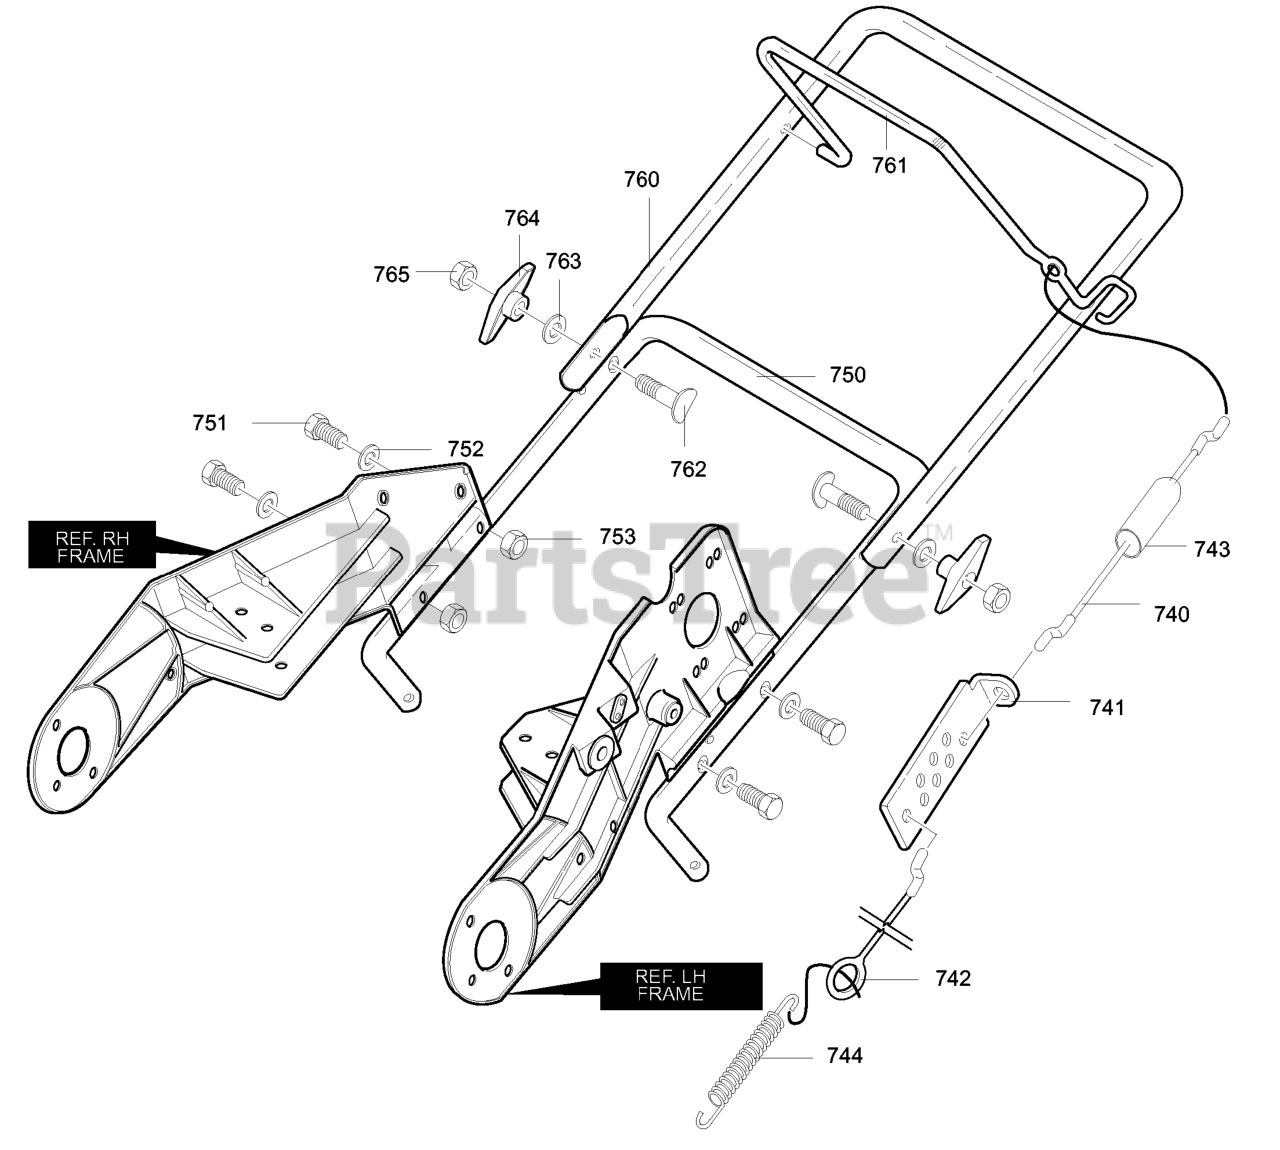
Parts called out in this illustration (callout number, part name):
740	CABLE, UPPER CONTROL
741	LF BRKT, CABLE ADJ
742	CABLE, LOWER CONTROL
743	BOOT, CLUTCH SPRING
744	SPRING, EXTENSION
750	HANDLE, LOWER
751	SCREW, 1/4-20X1.25
752	WASHER, FLAT.
753	NUT, 1/4-20
760	HANDLE, UPPER
761	BAIL, CONTROL
762	BOLT, 5/16-18X2.OO
763	WASHER, FORM
764	KNOB, T 3.00 WD PLAS BLA
765	NUT, 5/16-18 REGHEX
